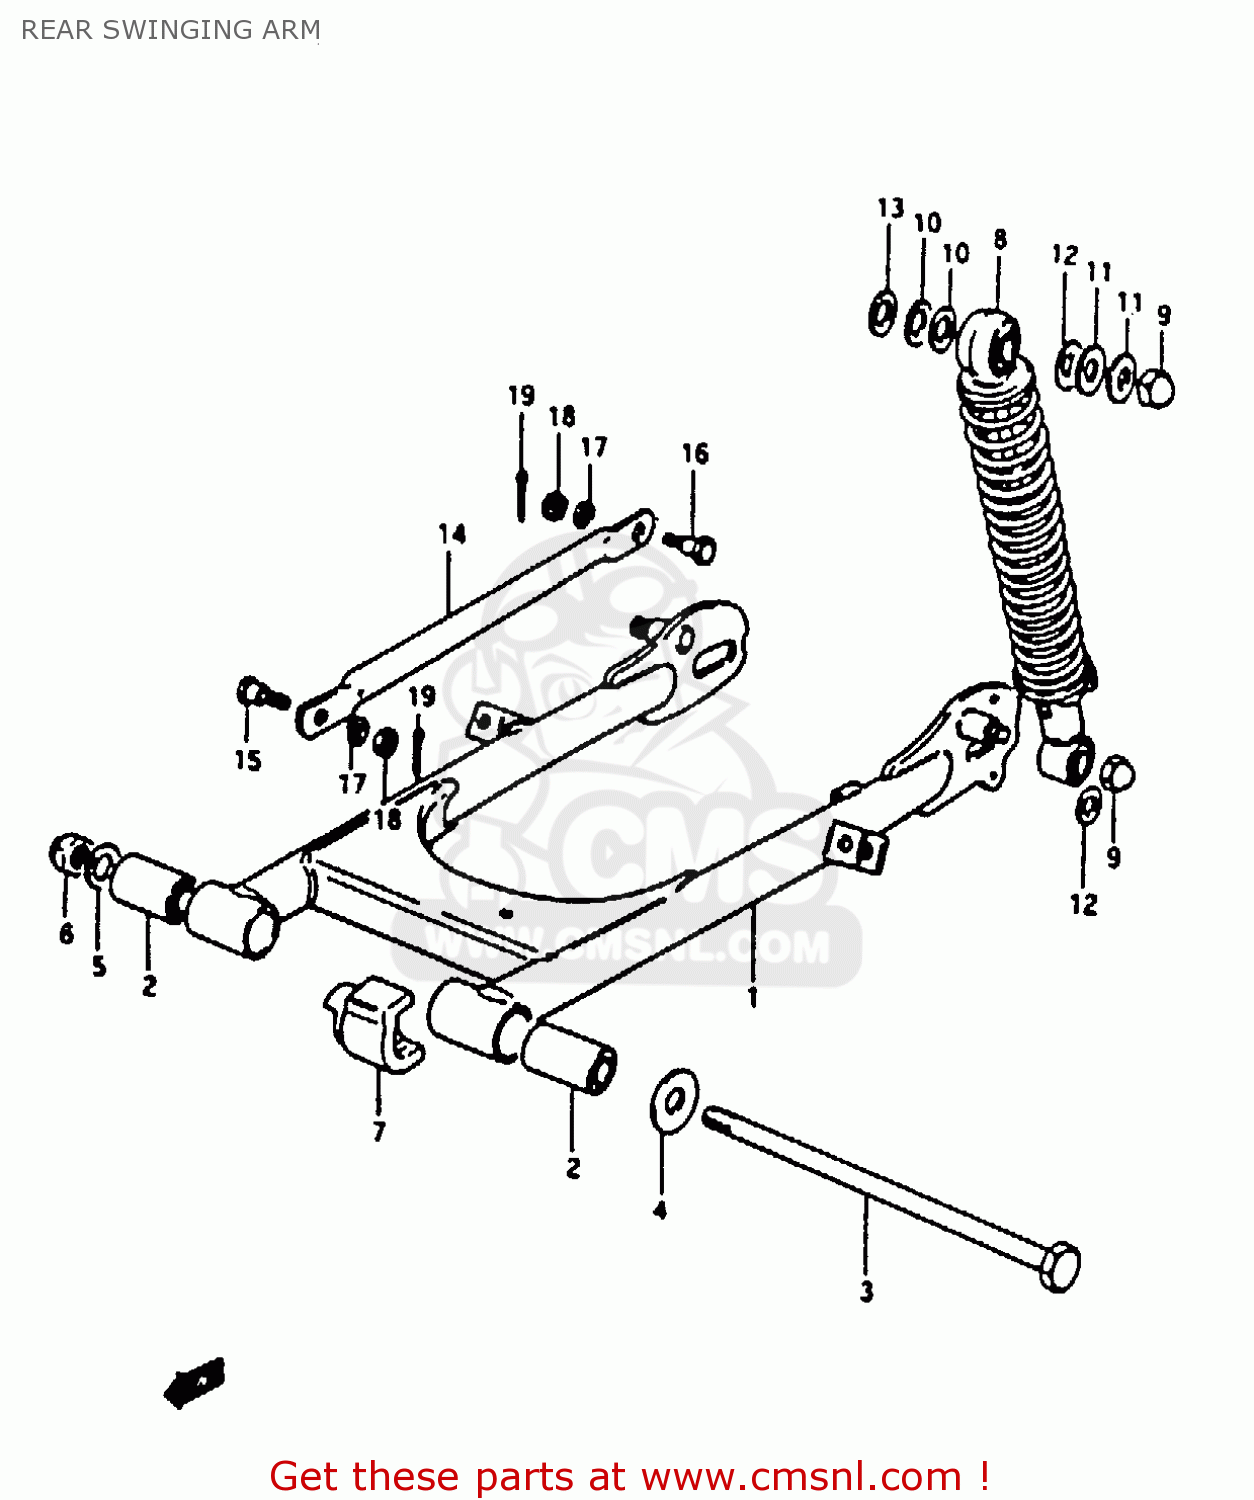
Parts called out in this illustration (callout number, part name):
1	SWINGING ARM SET, REAR (BLACK)
2	BUSH(12X24X44)
3	SHAFT,REAR SWING ARM
4	WASHER(12.5X32X2.3)
5	WASHER
6	NUT
7	BUFFER,CHAIN TOUCH DEFENSE
8	ABSORBER ASSY, REAR SHOCK
9	NUT
10	WASHER
11	WASHER
12	WASHER(10.5X24X3.2)
13	WASHER (12.5X24X3.2)
14	LINK,REAR TORQUE
15	BOLT(8X22.5)
16	BOLT(8X26.5)
17	LOCK WASHER
18	NUT
19	PIN 20X20
